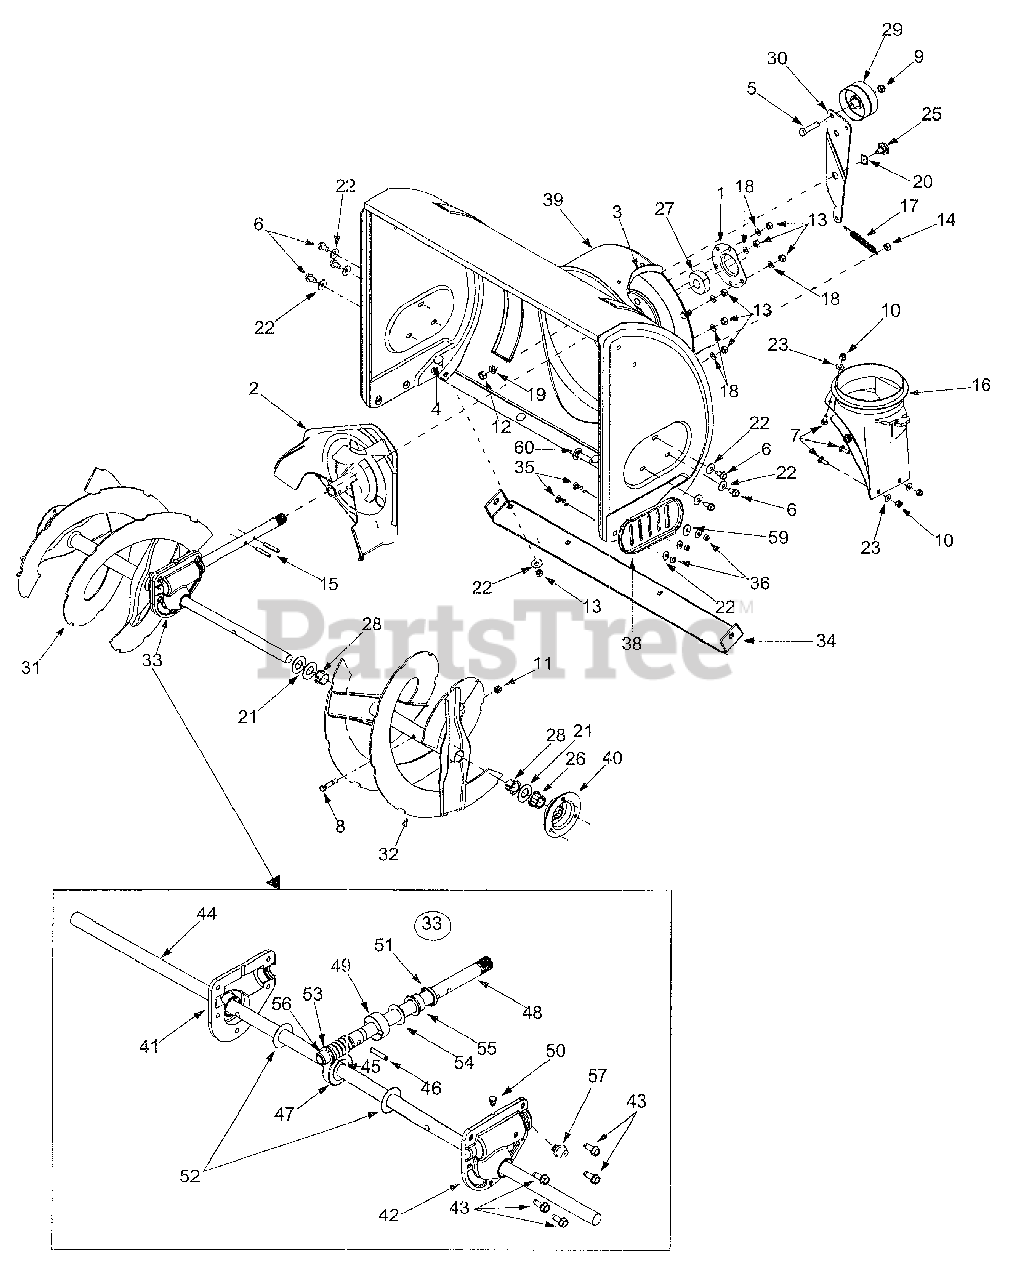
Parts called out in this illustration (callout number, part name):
1	Bearing Housing
4	Carriage Bolt 5/16-18 x .75" Gr.2
5	Hex Screw 3/8-24 x 1.6" Gr.5
6	Hex Screw 5/16-18
7	Carriage Screw 1/4-20 x .75"
8	Shear Bolt 5/16-18 x 1.5"
9	Jam Nut 3/8-24
10	Hex Lock Nut 1/4-20
11	Hex Lock Nut 5/16-18
12	Hex Nut 3/8-16 Gr.2
13	Hex Nut 5/16-18 Gr.5
14	Hex Patch Nut 5/16-18
16	Chute Adapter
17	Extension Spring
18	Lock Washer
20	Wave Washer
22	Belleville Washer
25	Shoulder Screw
26	Hex Flange Bearing
27	Flange Ball Bearing
28	Flange Bushing
35	Carr. Bolt: 5/16-18 x 0.75
36	Hex Nut: 5/16-18 Gr.5
41	RH Housing
42	LH Housing
43	TT Screw, 1/4-20 x .75
44	Spiral Axle, 26"
45	Hi-Pro Key, 3/16 x 5/8
46	Spring Spiral Pin, .25 x 1.25
47	Worm Gear, 20T
48	Worm Shaft
49	Thrust Collar
52	Flat Washer .76 x 1.5 x .030
53	Flat Washer .508 x 1.0 x .020
54	Flat Washer .76 x 1.5 x .060
55	Flange Bearing .75 x 1.0 x .59
56	Flange Bearing .503 ID x .75 OD
57	Grease Fitting
60	Carriage Screw: Special
